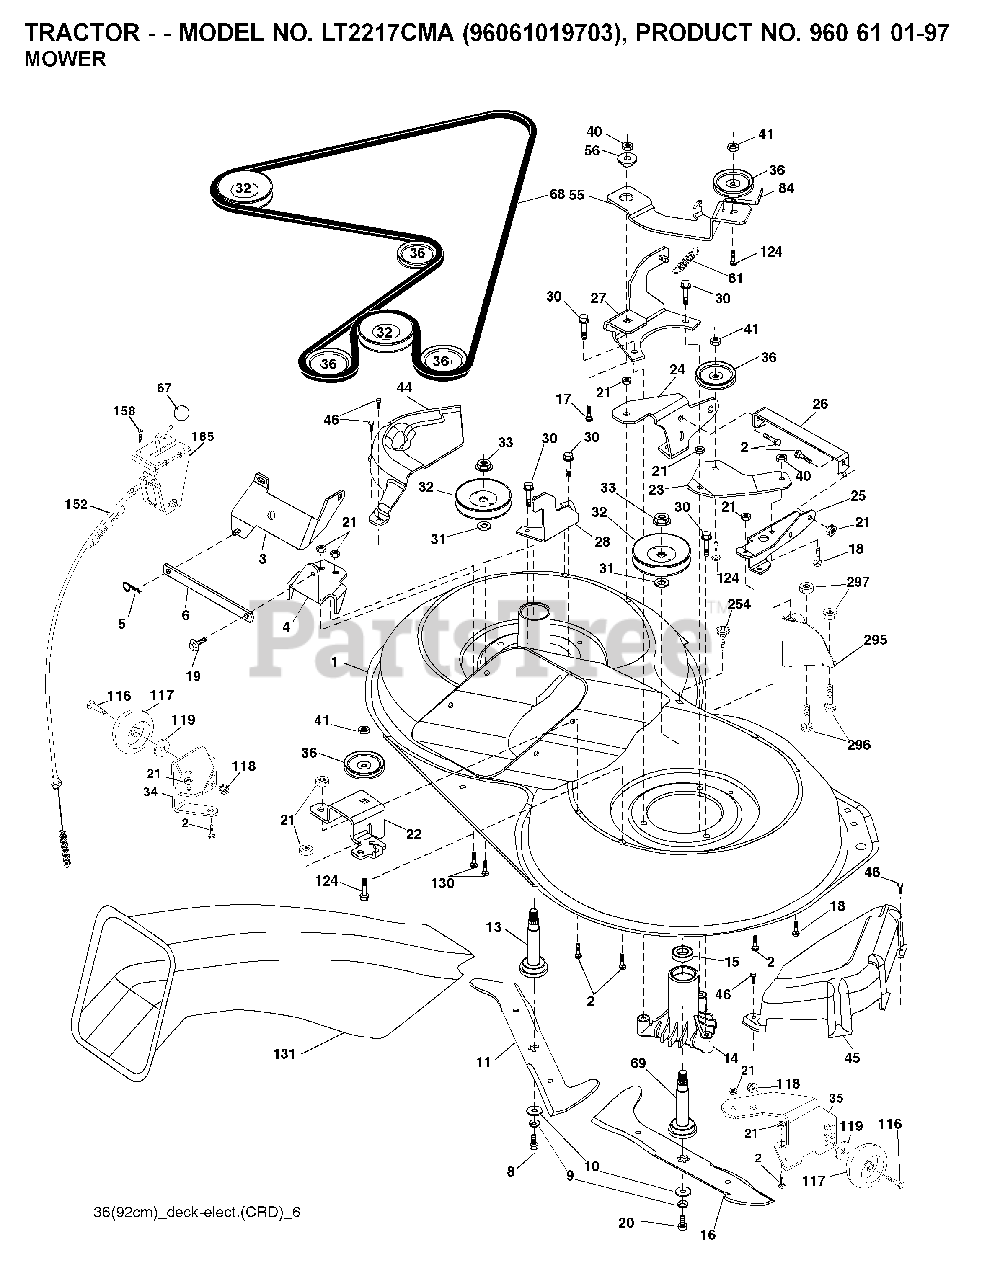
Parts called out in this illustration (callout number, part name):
2	BOLT
3	BRACKET
5	RETAINER-SPRNG RB
6	BAR SWAY
9	LOCKWASHER
10	WASHER.BLADE
13	SHAFT ASM VENT
14	HSG MANDREL
17	BOLT.3/8-14X1.25
18	BOLT
19	BOLT SHD 5/16-18
21	LOCKNUT
24	BRACKET
25	BRACKET
28	BRACKET
30	SCREW, WASHER HEAD
31	WASHER.SPACER.MANDREL
32	PULLEY MANDREL
33	NUT.FLANGE.LOCK.TOP
36	PULLEY.IDLER.4.25
40	LOCKNUT
41	NUT LOCK FLG 3/8-16 UNC
45	MANDREL COVER
46	SCREW.1/4-20X5/8
56	SPACER.RETAINER.MOWER
67	KNOB T (3/8 HOLE)
69	SHAFT.ASM.W/LWR.BRG.RH.THREAD
84	KEEPER, BELT IDLER
116	BOLT.SHOULDER.3/8-16X3-5/8
117	WHEEL. GUAGE RALLY
118	NUT LOCK FLG 3/8-16 UNC
124	BOLT.3/8-16X1.50
131	CHUTE BAGGER
158	SCREW
185	HEAD ASM. CABLE CLUTCH
254	SCREW 3/8-16X1
296	BOLT
297	NUT CENTERLOCK
